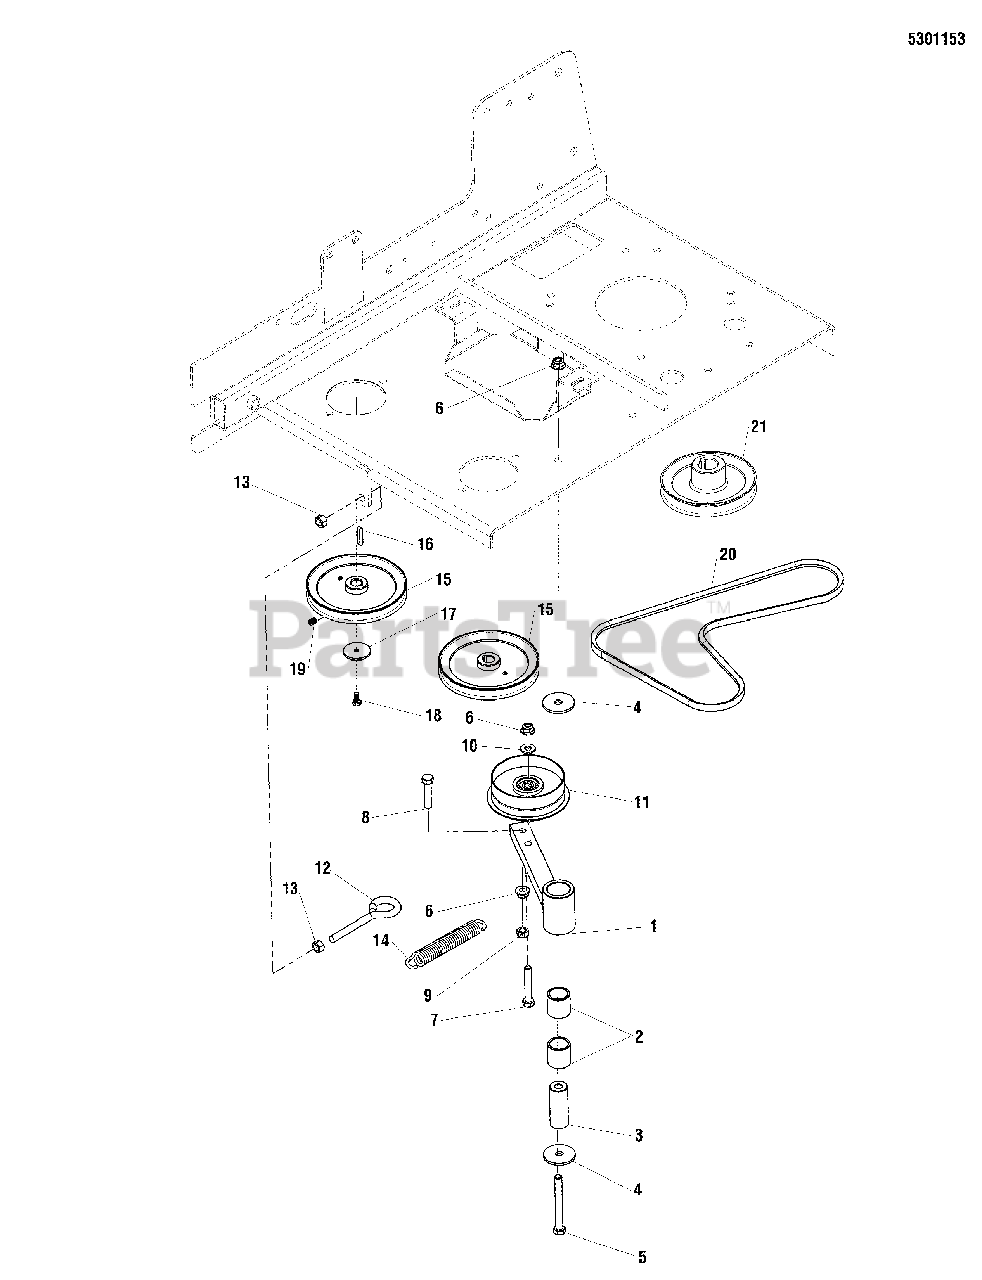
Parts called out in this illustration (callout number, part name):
1	See "PUMP DRIVE [Cast Idler Arm for replacing Steel Pump Drive Idler Arm]"
2	BUSHING, BRASS, 1.25X1X1.25
3	SPACER, .39 X 1.00 X 2.55
4	WASHER, .41 X 1.75 X .14
5	BOLT, 3/8-16 X 3-1/2 GD5 YZ
6	NUT, 3/8-16 HEX NYLOCK FLANGE
7	BOLT, 3/8-16 X 2-1/4 GD5 YZ
8	BOLT, 3/8-16 X 1-3/4 GD5
9	NUT, 3/8-16 HEX SIDE LOCK
10	WASHER, 3/8 GD.9 FLAT
11	PULLEY, FLAT IDLER, 4.06 X .75 W
12	SCREW HOOK, 3/8-16 X 4-1/4
13	NUT, 3/8-16 HEX
14	SPRING, EXTENSION, SWIVEL END
15	PULLEY, PUMP DRIVE
16	KEY, 5MM SQ. W/ RADIUS
17	WASHER, .265 X 1.50 X .109, YZ
18	CAPSCREW,HEX HEAD M6-1.0X 14MM
19	SET SCREW, 5/16-18 X 3/8, KNURL, W/PATCH
20	BELT, #7-9502
21	PULLEY, CRANKSHAFT
